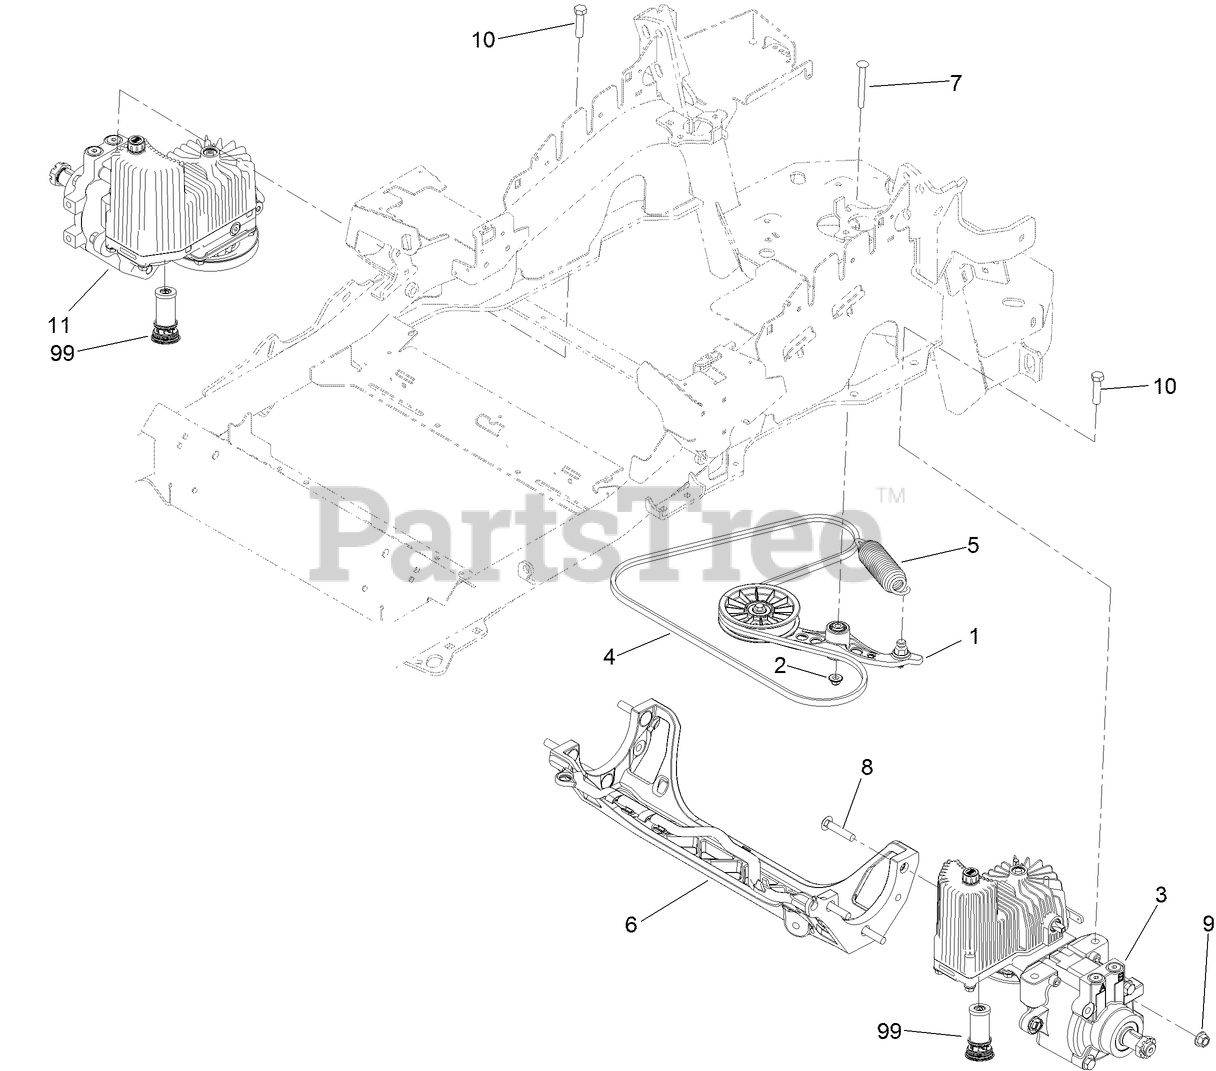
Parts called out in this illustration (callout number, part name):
1	PUMP IDLER ASM
2	NUT-FLANGE, NI
3	HYDRO-LH 12CC NO FAN
4	BELT-V
5	EXTENSION-SPRING
6	CRADLE-HYDRO
7	BOLT-SHOULDER, CARRIAGE
8	SCREW-CARR
9	NUT-LOCK
10	SCREW-HH
11	HYDRO-RH 12CC NO FAN
99	FILTER-HYDRO
